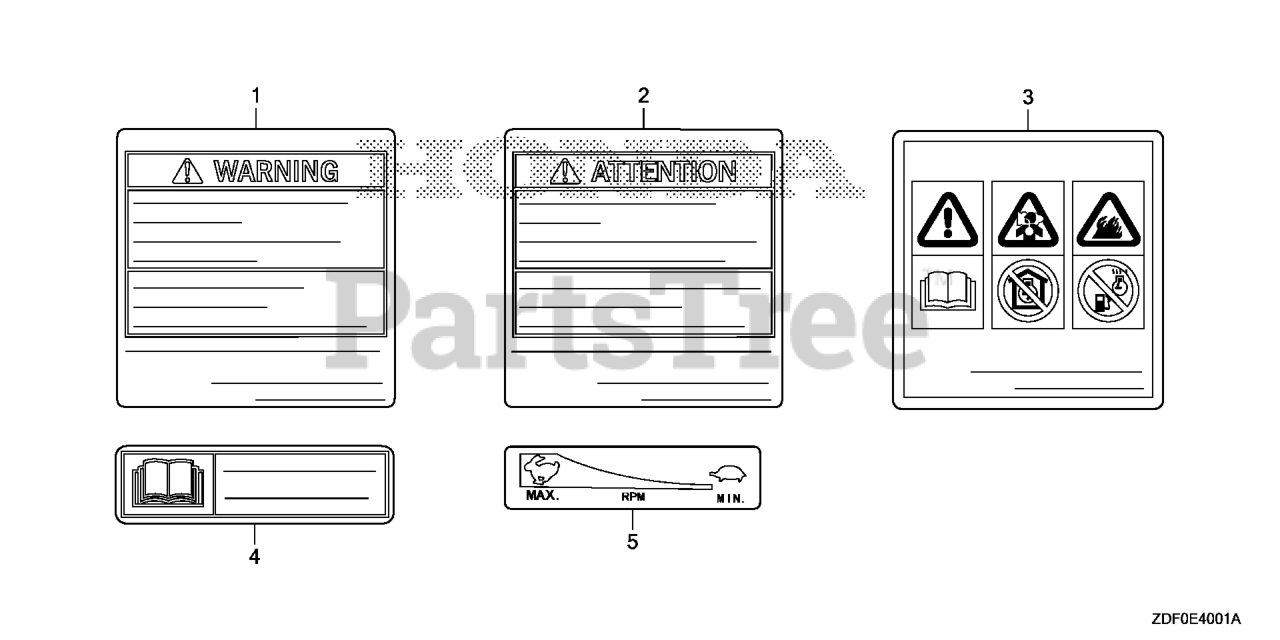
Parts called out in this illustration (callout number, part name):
1	MARK, OPER CAUTION
2	MARK, OPER CAUTION
5	MARK, THROTTLE INDICATION
